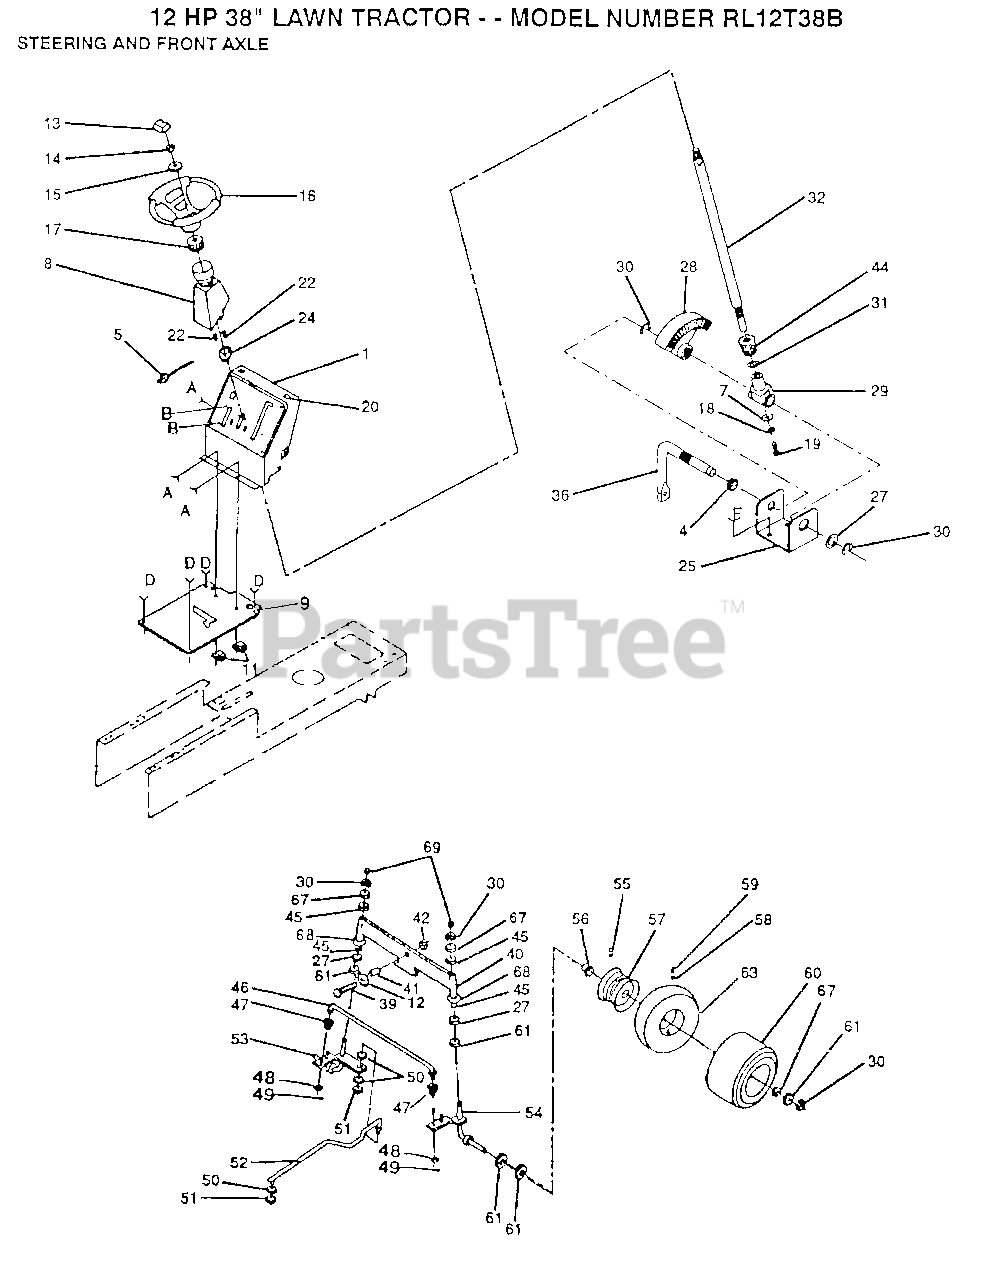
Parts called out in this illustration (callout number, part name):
2	SCREW
4	NYLINER T
6	SCREW LT
8	"TUBE, STR SHAFT"
10	SCREW LT
11	CLIP T
13	INSERT-WHEEL LT
15	WASHER
17	ADAPTER LT
18	LOCKWASHER
19	"SCREW,SPECIAL"
24	"BUSHING,STEERING"
25	"BRKT,STEERING"
26	SCREW
27	WASHER .T
29	SUPPORT.SHAFT
30	RING
31	THRUST WASHER
39	BOLT LT
41	BEARING
42	"NUT-LOC,FLANGE LT"
44	"GEAR,PINION"
45	COL. SRTG. BEAR.
48	WASHER
49	COTTER PIN
50	LOCKWASHER
53	SPINDLE-LH LT
55	FITTING LT
56	"FLANGE, BEARING"
58	VALVE CAP
59	VALVE STEM LT
61	WASHER
63	TUBE.5.3/4.5/6
67	WASHER
68	WASHER
69	CAP
